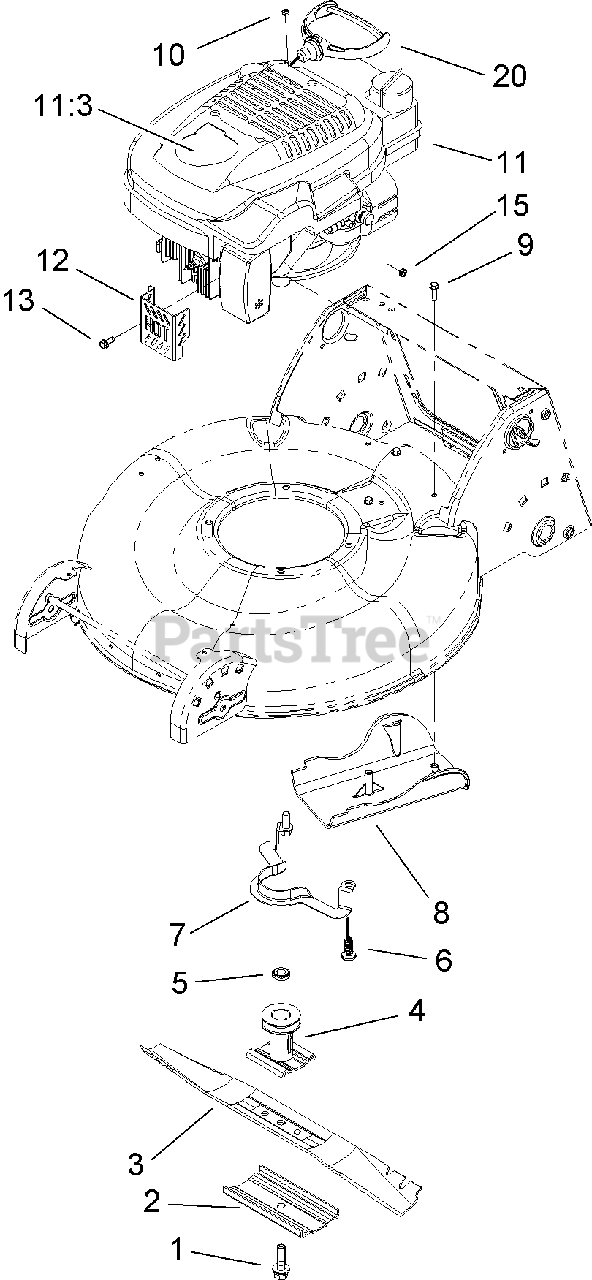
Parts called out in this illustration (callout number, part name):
1	BOLT-BLADE
2	SUPPORT-BLADE
3	BLADE-21 INCH
4	BLADE DRIVER ASM
5	Spacer-Driver
6	SCREW
8	COVER-BELT
9	SCREW-HWH
10	STOP-ROPE
11:3	DECAL-RECOIL
12	GUARD-MUFFLER
13	SCREW-HWH
15	NUT-KEPS
20	HANDLE-RECOIL
